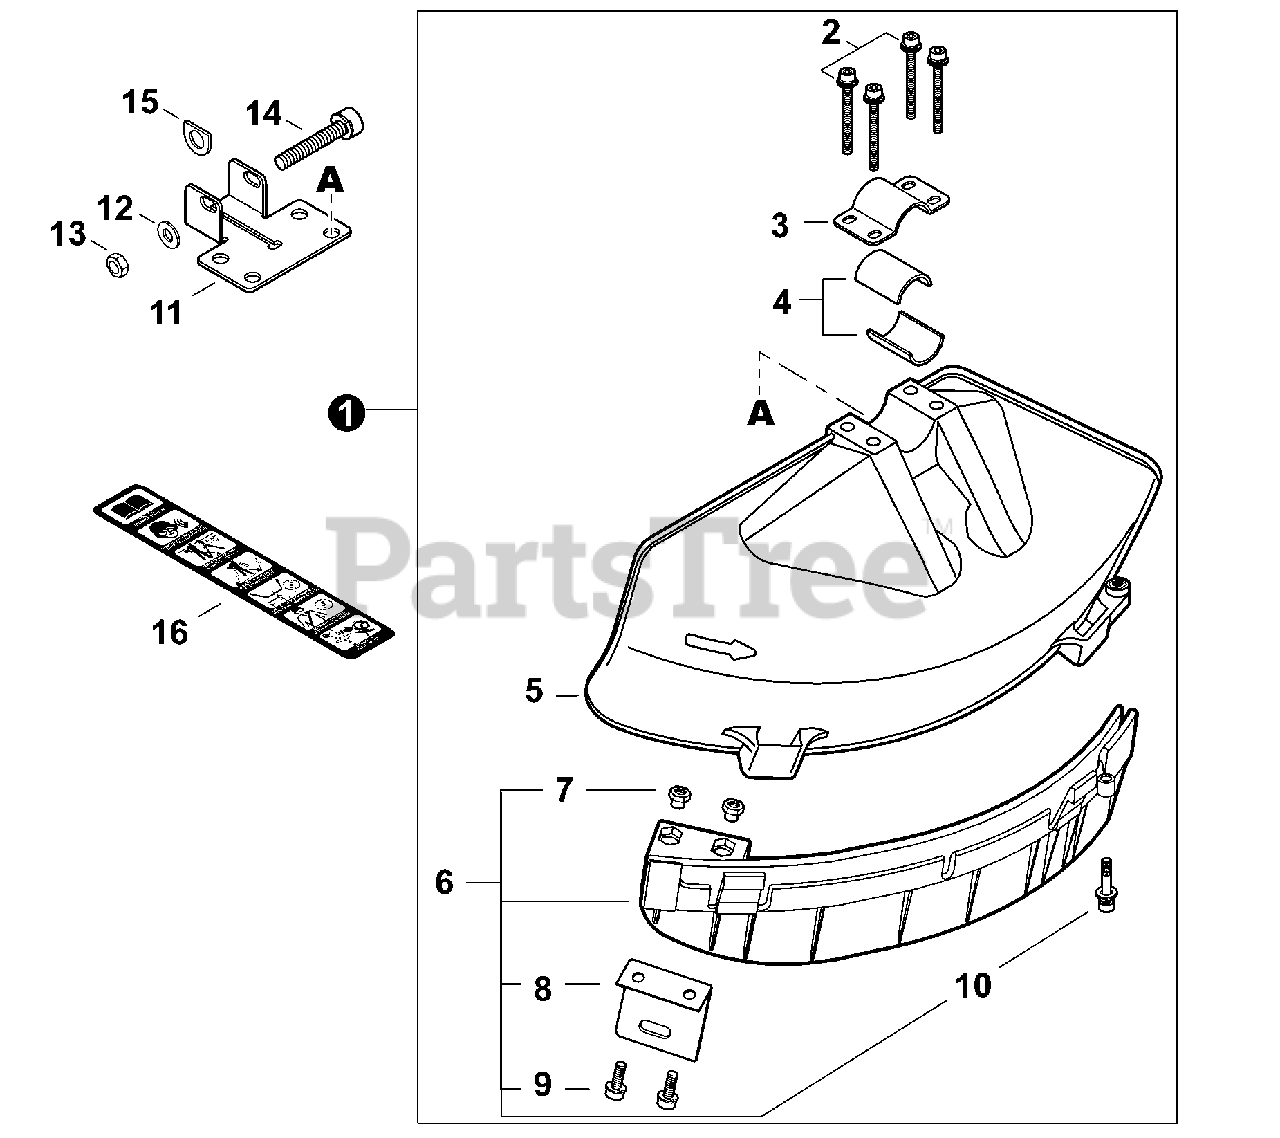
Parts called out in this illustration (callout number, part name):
1	DEBRIS SHIELD KIT
2	BOLT M5x45
3	CLAMP, UPPER
4	SPACER 24
5	SHIELD, DEBRIS - BLADE
6	EXTENSION ASSY, DEBRIS SHIELD
9	BOLT 5x16
10	BOLT M5x22
11	PLATE, SHIELD MOUNTING
12	WASHER 5.5x12x0.8
14	BOLT M5x40
15	D-WASHER
16	LABEL - CAUTION (BLADE CAPABLE)
